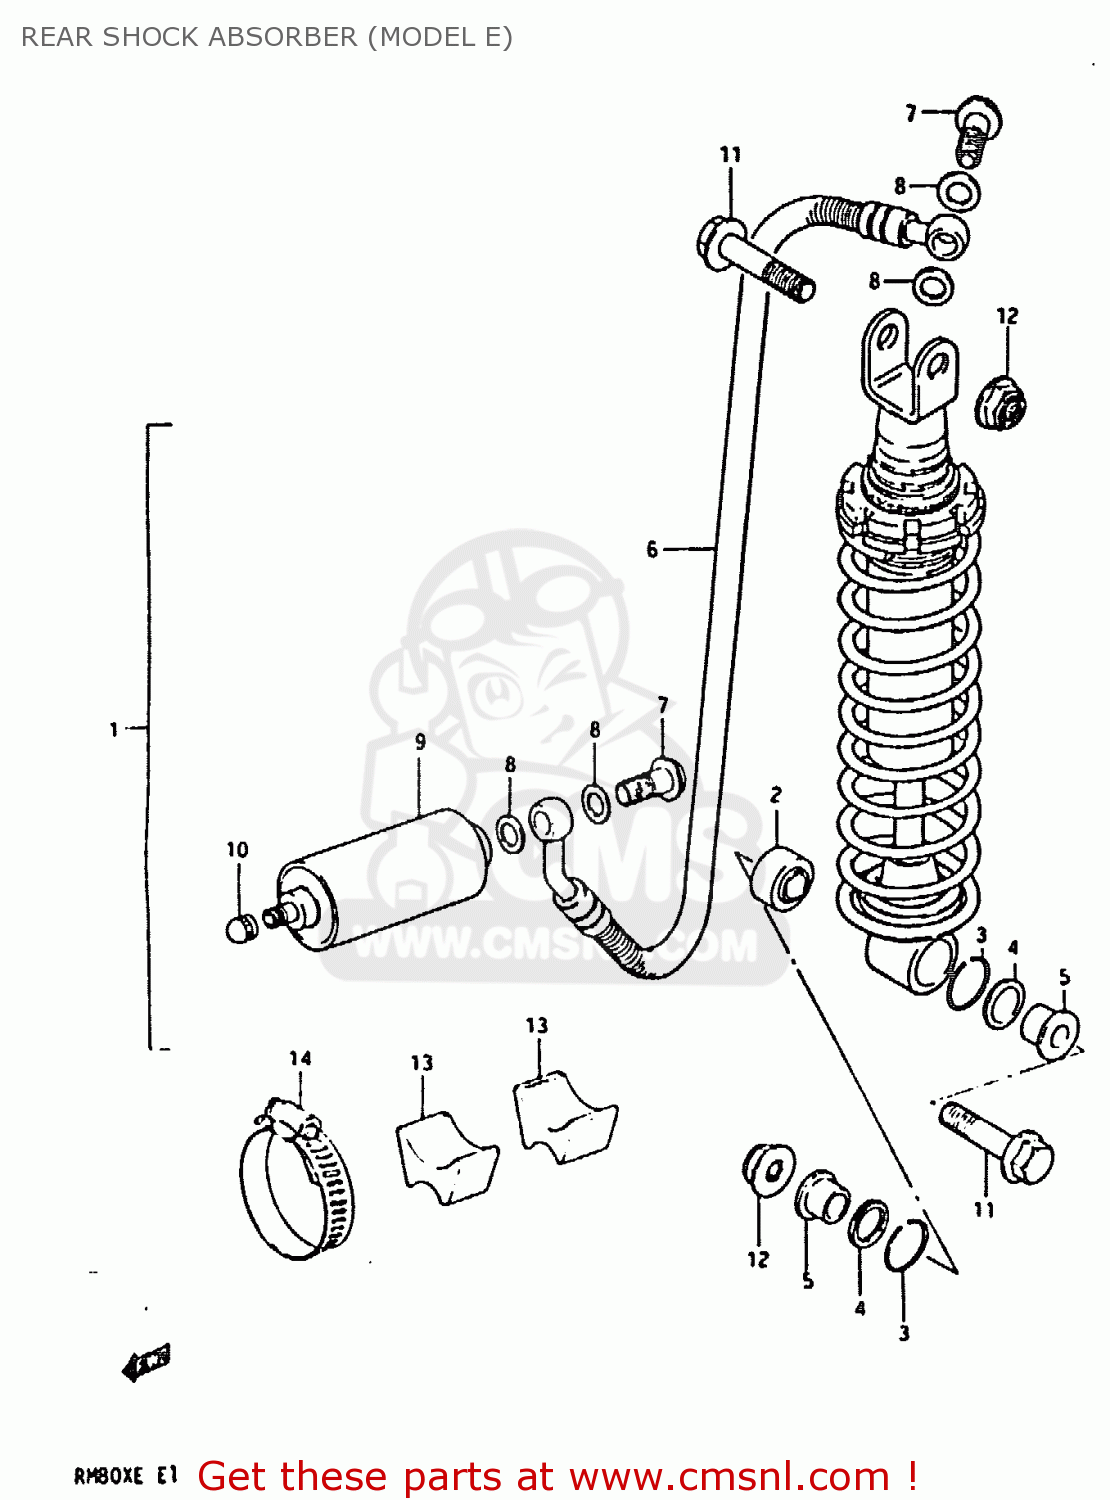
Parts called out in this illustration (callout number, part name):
1	ABSORBER ASSEMBLY,REAR SHOCK
2	BEARING,REAR SHOCK ABSORBER
3	RING
4	DUST SEAL
5	SPACER
6	HOSE,REAR SHOCK ABSORBER
7	BOLT,REAR SHOCK ABSORBER
8	WASHER
9	RESERVE TANK,REAR SHOCK
10	CAP,VALVE AIR
11	BOLT(10X50)
12	NUT
13	CUSHION,REAR SHOCK ABSORBER
14	CLAMP
